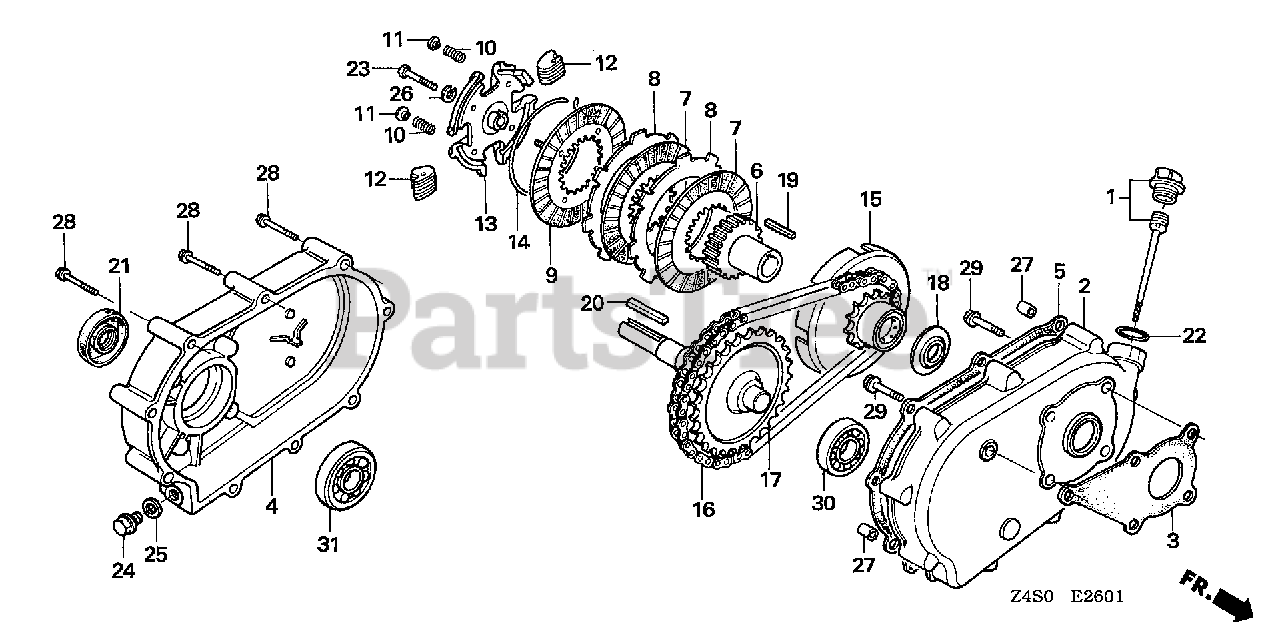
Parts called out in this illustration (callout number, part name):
1	CAP ASSY., OIL FILLER
2	CASE, REDUCTION
3	GASKET, REDUCTION CASE
4	COVER, REDUCTION
5	GASKET, REDUCTION COVER
6	CENTER, CLUTCH
7	DISK, CLUTCH FRICTION
8	PLATE, CLUTCH
9	PLATE, CLUTCH PRESSURE
10	SPRING, CLUTCH FREE
11	HOLDER, CLUTCH SPRING
12	WEIGHT, CLUTCH
13	HOLDER, CLUTCH WEIGHT
14	CENTER, CLUTCH WEIGHT
15	SPROCKET, DRIVE
16	CHAIN, DRIVE (RK428SH-36LE)
17	SHAFT, P.T.O. (28T)
18	WASHER, THRUST (20MM)
19	KEY (5MM)
20	KEY (7X7X33)
21	OIL SEAL (30X50X7)
21	OIL SEAL (PJ30507)
22	O-RING (26X2.7)
23	BOLT, HEX. (8X35)
24	BOLT, DRAIN PLUG (12MM)
25	WASHER, DRAIN PLUG (12MM)
26	WASHER, SPRING (8MM)
27	PIN A, DOWEL (8X10)
28	BOLT, FLANGE (6X55)
29	BOLT, FLANGE (8X22) Use from Engine SN 1609607.
30	BEARING, RADIAL BALL (6205)
31	BEARING, RADIAL BALL (6206)
